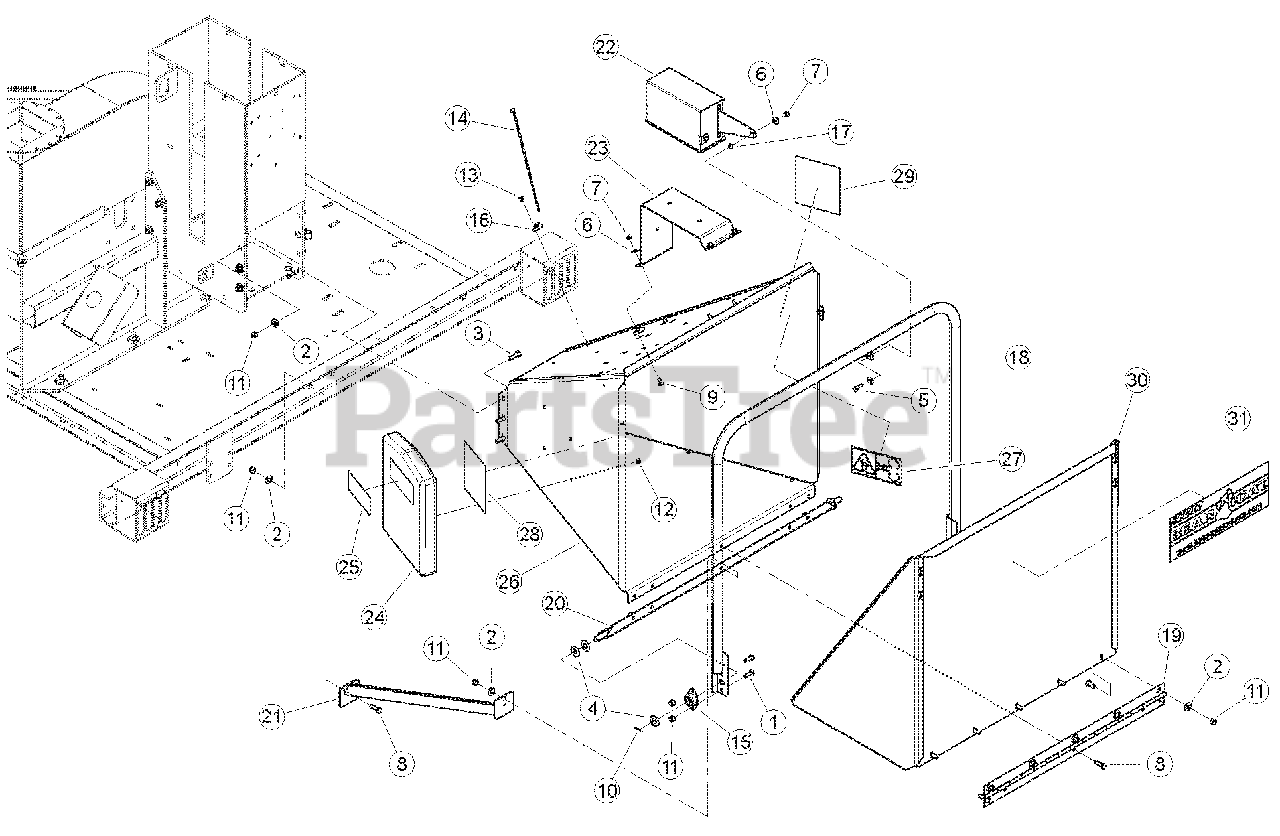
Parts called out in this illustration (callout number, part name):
1	BOLT, 3/8 X 1 HEX HD GR5 ZP
2	WASHER, 3/8 FLAT ZP
3	BOLT, 3/8 X 1-1/2 CRG GR5 ZP
4	WASHER, 5/8 SAE FLAT ZP
5	BOLT, 5/16 X 1 HHCS GR5 NC ZP
6	WASHER, 5/16 FLAT ZP
7	NUT, 5/16 NE NYLOCK ZP
8	BOLT, 3/8 X 1-1/4 HEX HD GR5 ZP
9	BOLT, 5/16 X 3/4 CRG GR5 NC ZP
10	PIN, 1/8 X 1.00 ZP COTTER
11	NUT, 3/8 NE NYLOCK ZP
12	RIVET, AL BLIND 1/4 X 1/2 DOME HEAD
13	RIVET, AL BLIND 1/4 X 3/4 DOME HEAD
14	STRAP, 11 IN. BLACK TIE
15	BEARING, SIDE FLNG MOUNT 5/8"
16	CLAMP, CABLE MOUNT
17	SPACER, IDLER PIVOT
18	WELDMENT, CONTROL ARM
19	HINGE, EXTENSION TRAY
20	WELDMENT, CONTROL PIVOT
21	WELDMENT, CHUTE SUPPORT
22	ASSEMBLY, SWITCH BOX
23	MOUNT, SWITCH BOX
24	ASSEMBLY, MANUAL CONTAINER SERVICE PART
25	DECAL, MUTILINGUAL MANUAL
26	ASSEMBLY, BIG CHIPPER CHUTE, SERVICE PART
27	DECAL, BLADE DANGER ISO
28	DECAL, FEED POSITION
29	DECAL, FEED POSITION
30	ASSEMBLY, CHUTE EXT. TRAY, SERVICE PART
31	DECAL, BEARCAT WEB
